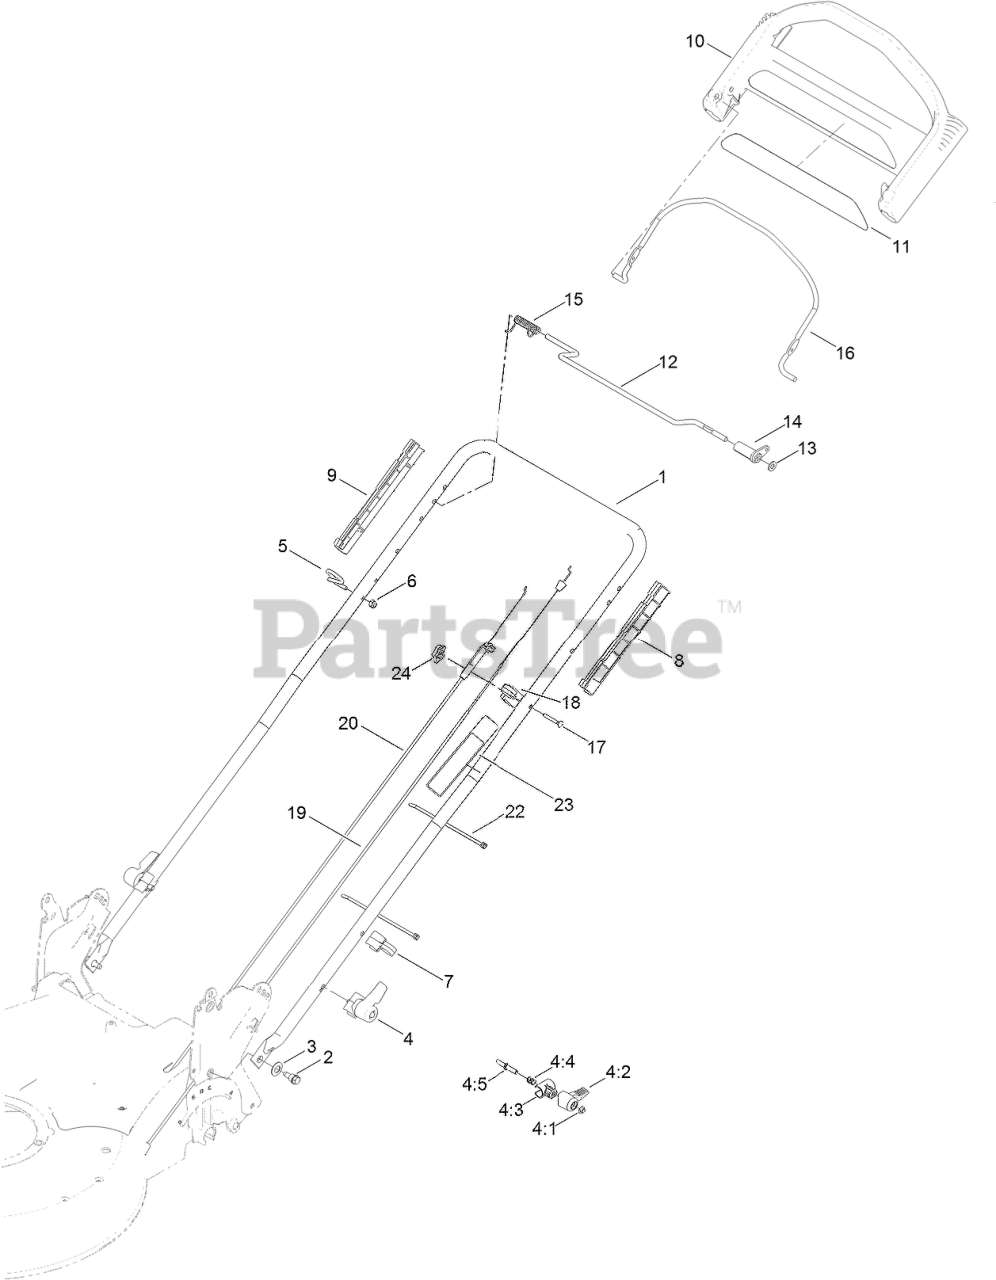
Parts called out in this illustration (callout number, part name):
2	BOLT-SHOULDER
3	WASHER-SPRING, CONICAL
4	QUICK RELEASE ASM
4:1	NUT-PUSH
4:2	LEVER
4:3	ANCHOR-SPRING
4:4	SPRING-COMPRESSION
4:5	ROD-RELEASE
5	GUIDE-ROPE
6	NUT-LOCK, NI
7	GUIDE-CABLE
8	GUIDE-LH
9	GUIDE-RH
10	HANDLE-CONTROL
11	DECAL-HANDLE
12	BAR-CONTROL, TRACTION
13	WASHER-PLAIN
14	LEVER-TRACTION
15	Spring-Torsion
16	Bail-Brake
17	SCREW
18	ANCHOR-CABLE
19	CABLE-TRACTION
20	CABLE-BRAKE
22	TIE-CABLE
23	DECAL-TRACTION, ADJUST
24	KNOB-HANDLE, LOCKING
